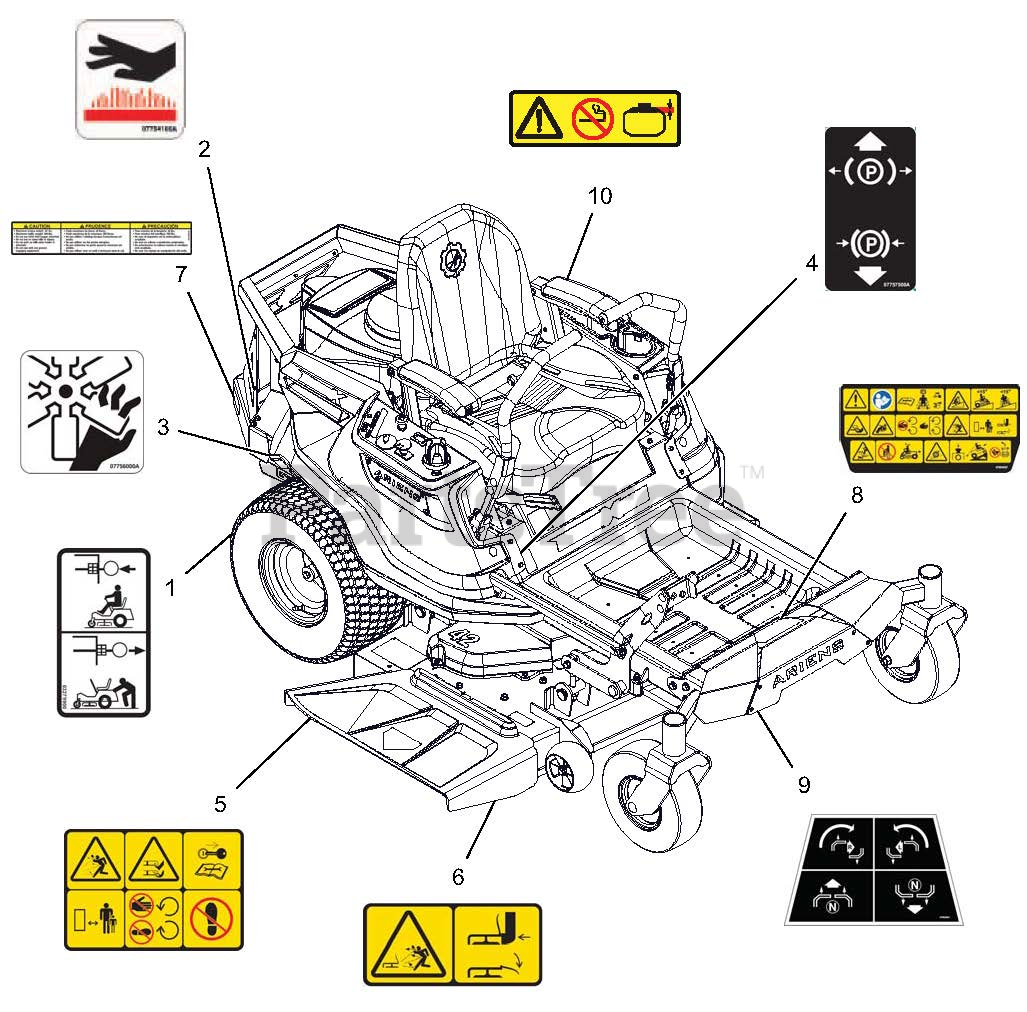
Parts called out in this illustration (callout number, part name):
1	DECAL, TRANSMISSION DISCONNECT
2	DECAL, HOT SURFACE
3	DECAL, DANGER FAN
4	DECAL, PARKING BRAKE LEVER
5	DECAL, SAFETY - MOWER DECK
6	DECAL, SAFETY - DECK GUARDING
7	DECAL, TRAILER HITCH
8	DECAL, MAIN SAFETY
9	DECAL, STEERING
10	DECAL, FUEL WARNING
